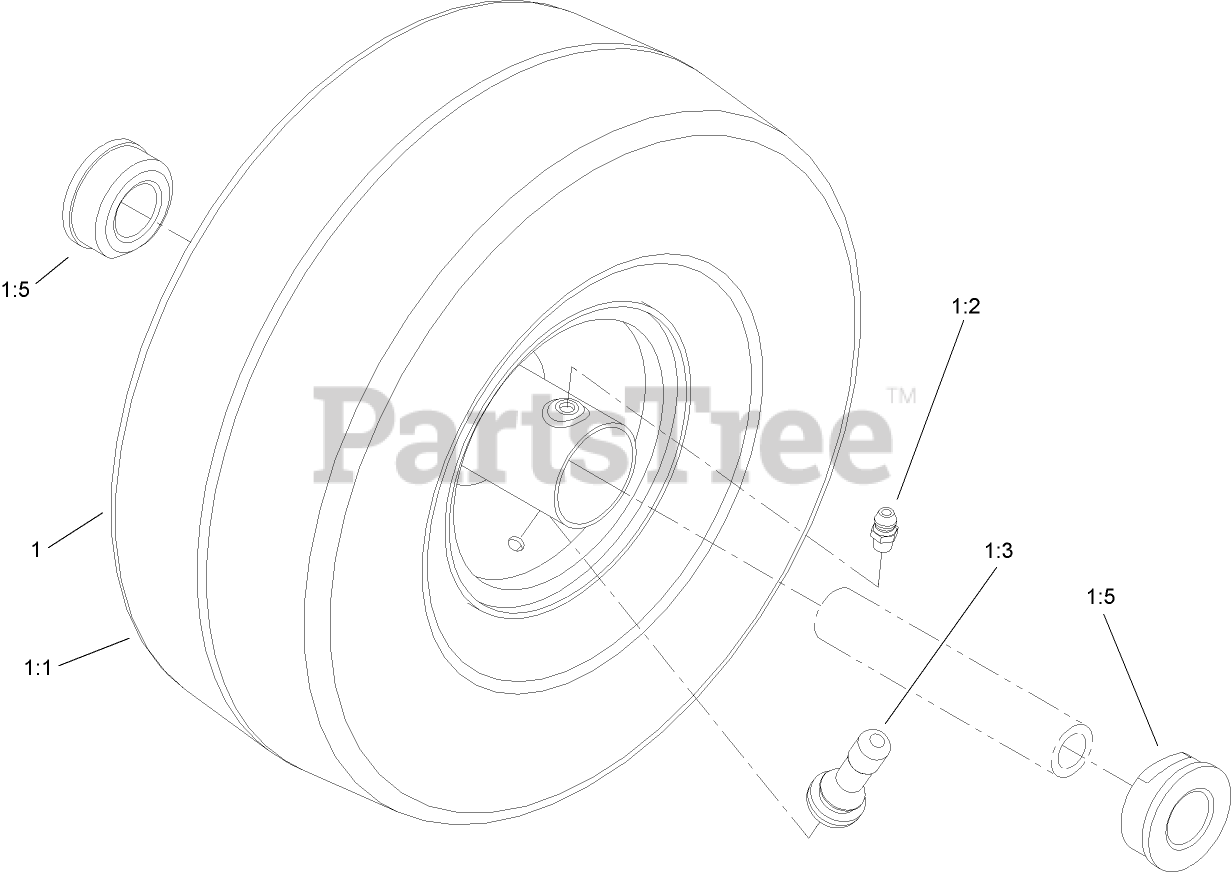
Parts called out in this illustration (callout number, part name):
1	CASTER WHEEL ASM (Kenda)
1:1	TIRE-SMOOTH
1:2	FITTING-GREASE
1:3	STEM-VALVE
1:5	BEARING-OUTSIDE
